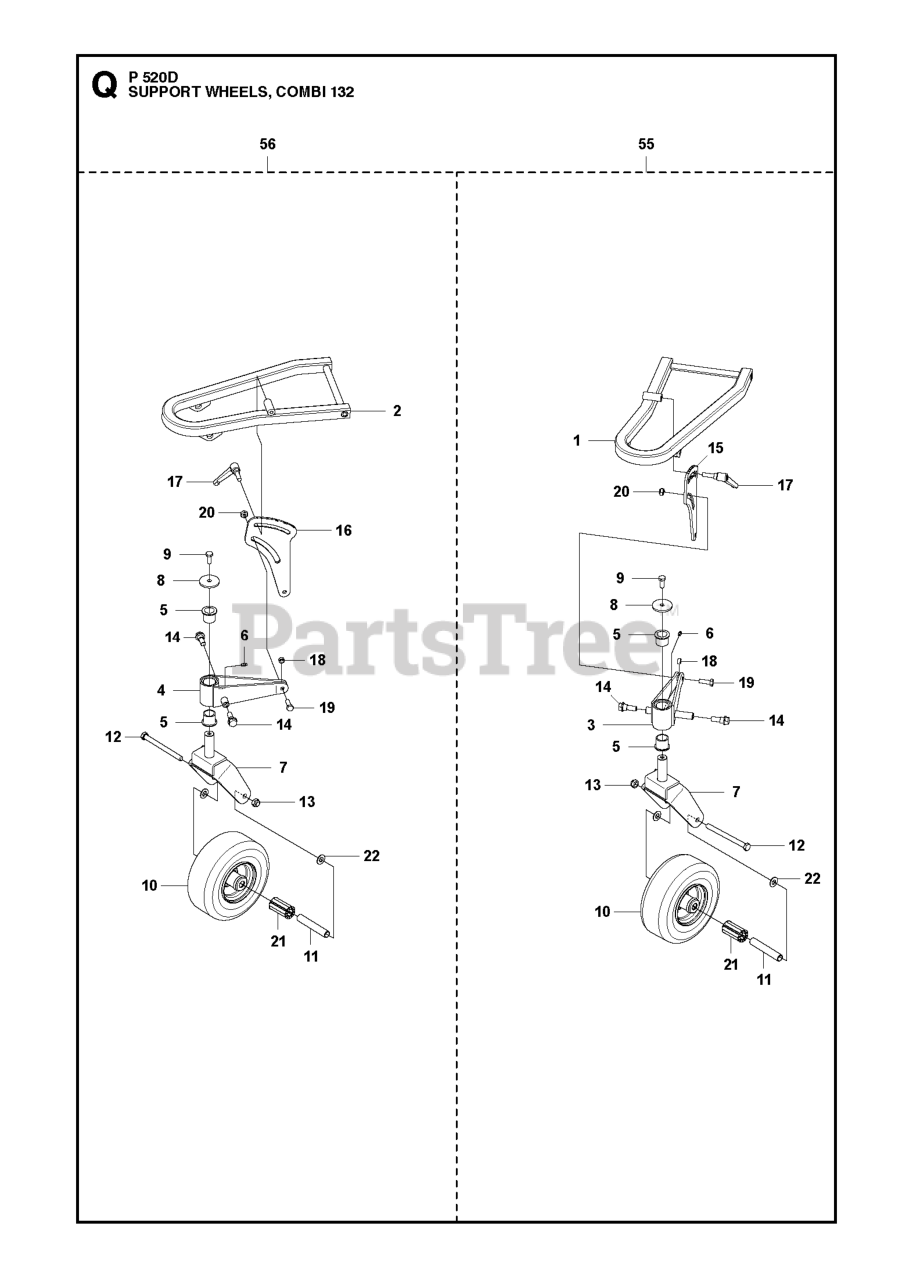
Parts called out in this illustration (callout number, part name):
1	SUPPORTING ARM LEFT
2	SUPPORTING ARM RIGHT
3	PIVOT WHEEL SUPPORT LEFT
4	PIVOT WHEEL SUPPORT RIGHT
5	BEARING BUSHING BRASS
6	GREASE NIPPLE
7	FORK PIVOT WHEEL
8	Washer
9	BOLT
10	TIRE/WHEEL.CASTER.9X3.5-4.SMOO
11	SPACER
13	NUT M12
14	BOLT
15	SHEET HEIGHT ADJUSTER
16	SHEET HEIGHT ADJUSTER
17	TURNING KNOB M 10
18	SLEEVE PIVOT WHEEL SUPPORT
19	SCREW
20	NUT
21	ROLLER BEARING
22	ENDCAP, NOTCHED
55	WHEEL SUSPENSION LEFT
56	WHEEL SUSPENSION RIGHT
